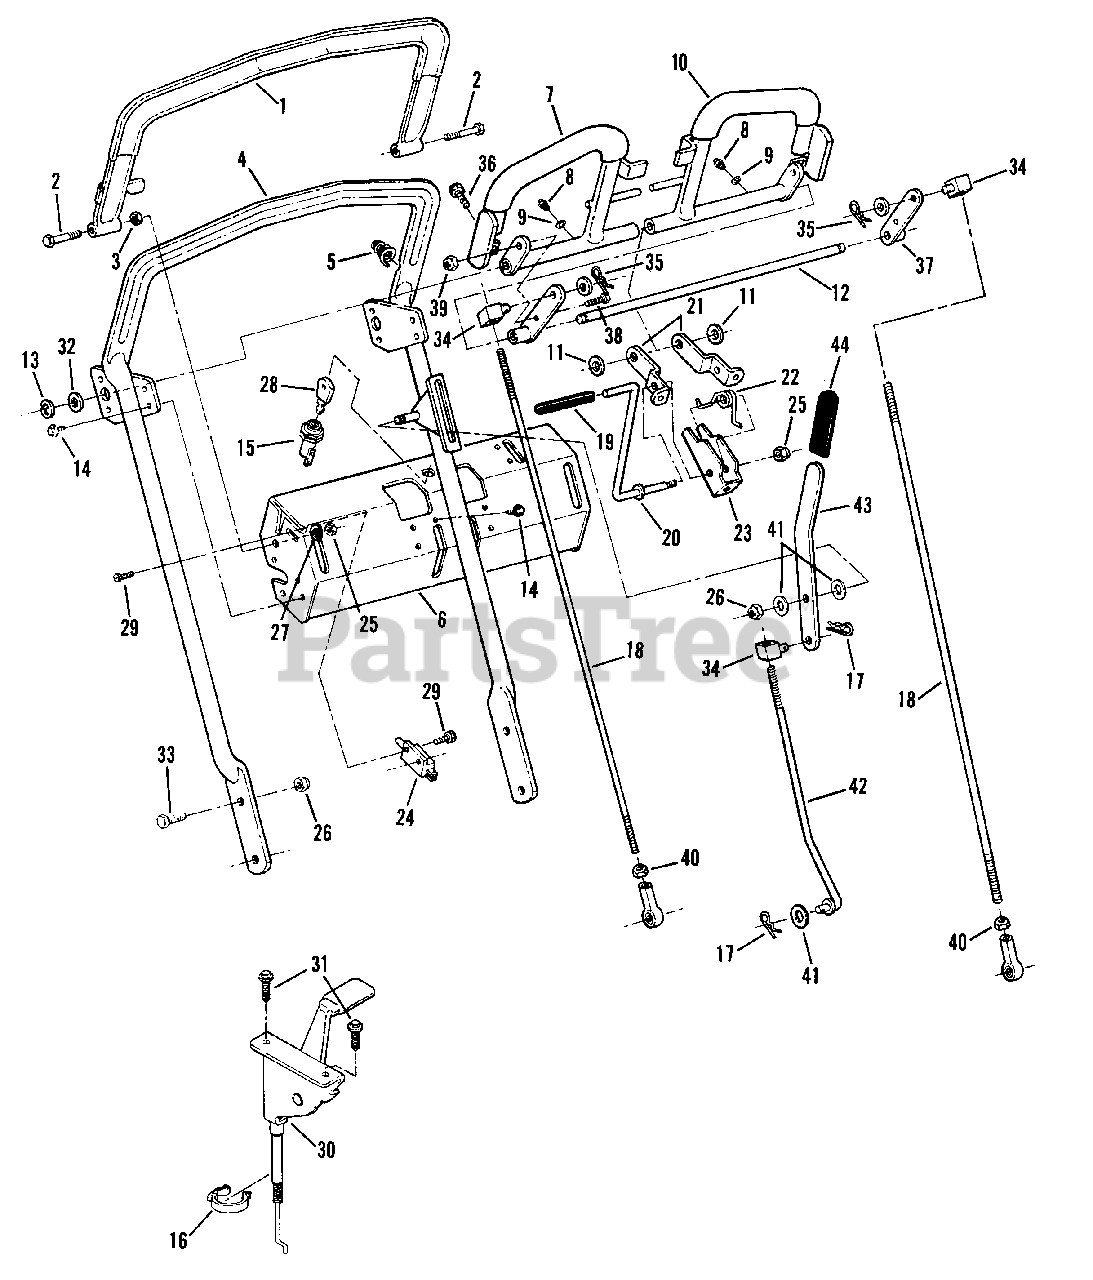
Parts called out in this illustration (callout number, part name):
1	BAIL, OPC (W/Grip)
2	BOLT, 1/4 - 20 x 1 2/3" Hex Head
3	NUT, 1/4 - 10 Hex
4	HANDLE, Loop
5	SPRING, Conical
6	CONTROL, Console
7	LEVER, Traction (Right Hand W/Grip)
8	ZERK, 1/4-28
9	WASHER, 1/4" Internal Tooth Lock
10	LEVER, Traction (Left Hand W/Grip)
11	WASHER, 1/2" Flat
12	ROD, Pivot
13	E-RING, 1/2"
14	SCREW, 1/4-20 x 1/2 Self-Tapping
15	SWITCH, On-Off
16	CLIP, Cable
17	HAIR-PIN COTTER
18	ROD, Traction
19	GRIP, Neutral Latch Red
20	LEVER, Neutral Latch
21	BRACKET, Neutral Mounting
22	SPRING, Neutral Torsion
23	LATCH
24	SWITCH, OPC
25	NUT, 1/4 - 20 Nyloc
26	NUT, 3/8 - 16 Nyloc
27	WASHER, 1/4 Flat
28	KEY, Switch (With Cover)
29	SCREW, #12 - 14 x 1/2 Self-Tapping
30	CONTROL, Throttle
31	SCREW, #10-24 x 1/2" Hex Washer Self-Tap (Torx)
32	BUSHING, 1/2" Machine
33	SCREW, 3/8 - 16 x 1" Hex Head
34	SWIVEL
35	HAIR-PIN
36	SCREW, 1/4-20 x 3/4"
37	TRACTION ARM
38	SCREW, 5/16 - 18 x 1" Hex Head
39	NUT, 5/16 Nyloc
40	NUT, 5/16-24 Hex
41	WASHER, 3/8" Flat
42	ROD, Blade Control
43	ARM, Blade Engage
44	GRIP
